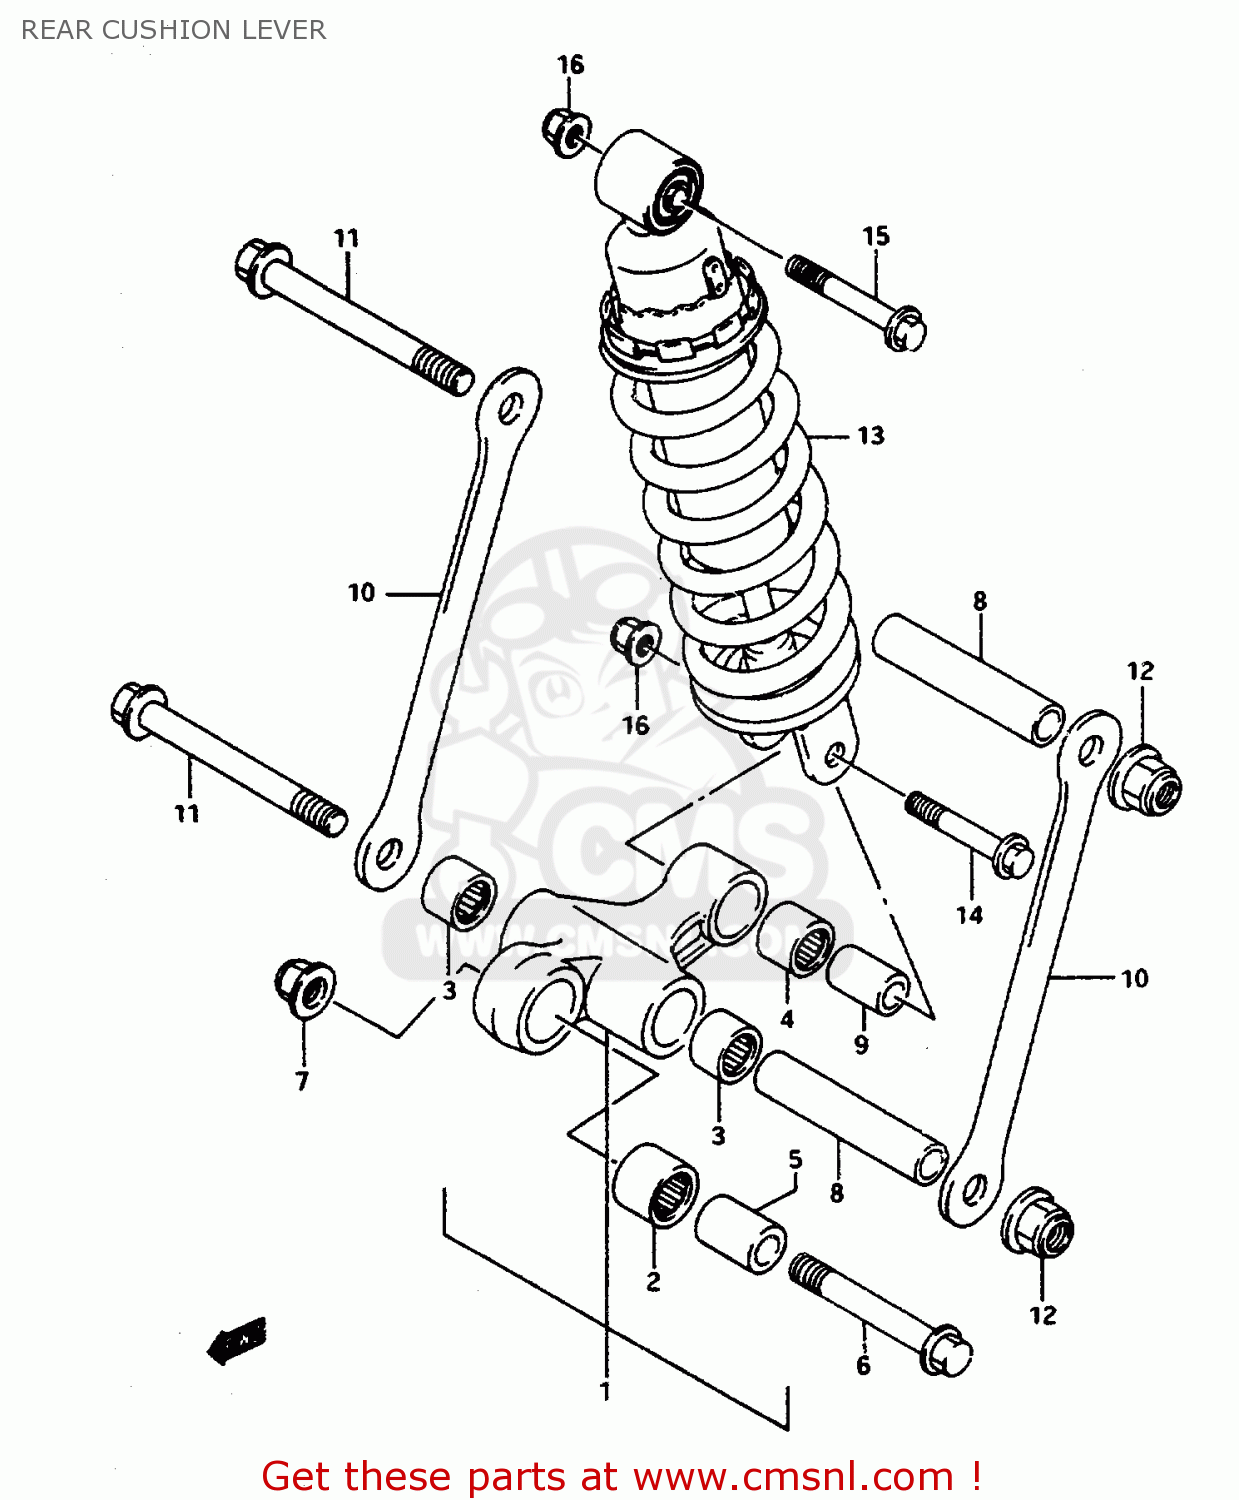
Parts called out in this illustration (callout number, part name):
1	LEVER SET,RR CUSHION
2	BEARING(20X27X26)
3	BEARING(17X24X25)
4	BEARING(17X24X26)
5	SPACER,REAR CUSHION LEVER
6	BOLT,CUSHION LEVER FR
7	NUT 12MM
8	SPACER(12X17X85)
9	SPACER,RR CUSHION LEVER
10	ROD,RR CUSHION LEVER
11	BOLT(12X115)
12	NUT 12MM
13	ABSORBER ASSY,RR SHOCK
14	BOLT(10X58)
15	BOLT(10X50)
16	NUT
